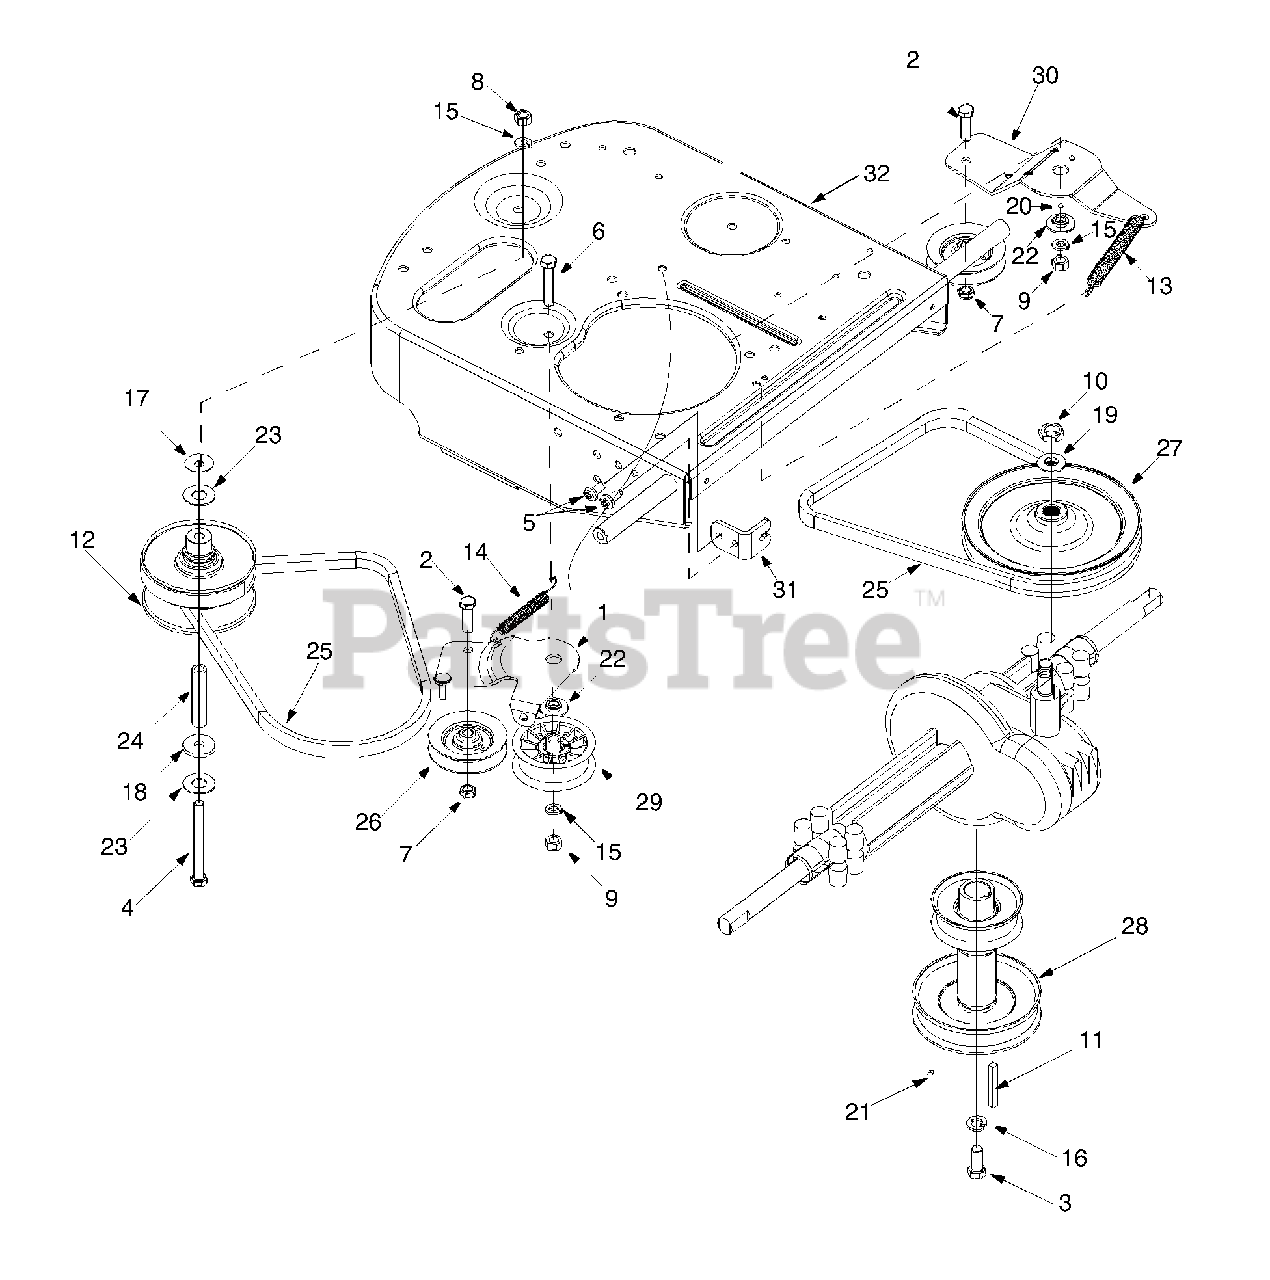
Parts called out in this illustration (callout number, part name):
1	Idler Bracket Assembly
2	Hex Screw 3/8-24 x 1.25
3	Hex Screw 7/16-20 x 1.0"
4	Cap Screw 3/8-24 x 3.75
5	Pan Head TL Screw 5/16-18 x .75
6	Hex Screw 3/8-16 x 2.0 Special
7	Jam Lock Nut 3/8-24
8	Hex Nut 3/8-24
9	Hex Nut 3/8-16
10	Hex Jam Nut 9/16-18 (Gr. 5)
11	Square Key
12	Variable Speed Pulley Assembly
13	Extension Spring
14	Extension Spring
15	Lock Washer
16	Lock Washer 7/16 I.D.
17	Bell Washer .406 I.D. x 1.13 O.D.
18	Flat Washer 3/8 x 1.25 O.D.
19	Belleville Washer .567 x 1.125 x .06
20	Grease
21	Grease
22	Shoulder Spacer
23	Bearing
24	Spacer
25	V-Belt
26	Idler Pulley
27	Transmission Pulley
28	Engine Pulley
29	Flat Idler Pulley
30	Idler Bracket
